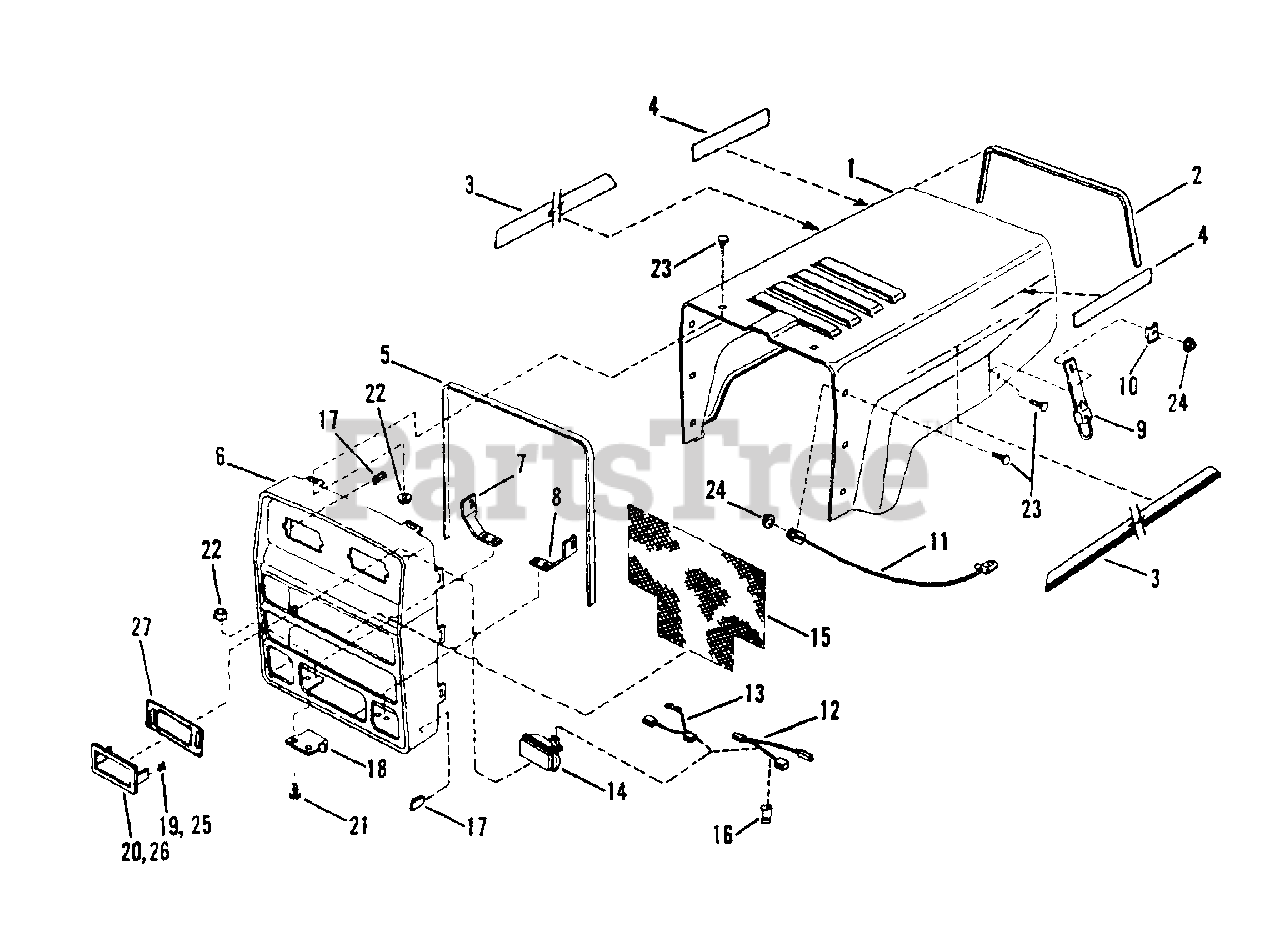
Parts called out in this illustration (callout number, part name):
1	HOOD, YT Series Tractor
2	TRIM, Hood
3	DECAL, Stripe
4	DECAL, Snapper
5	GASKET, Grill
6	GRILL
7	BRACE, Grill, R.H.
8	BRACE, Grill, L.H.
9	LATCH, Hood Retaining
10	CLIP, Hood Retainer
11	CABLE, Hood Stop
12	HARNESS, Head Lamp Wiring
13	HARNESS, Head Lamp Ground Wiring
14	HEAD LAMP
15	MESH, Grill
16	CLIP, Wiring Harness
17	CLIP
18	HINGE, Hood
19	CLIP, Head Lamp Mounting (Use 7017591 Wire Retainer & 7033211)
20	BEZEL, Head Lamp Mount (Use 7033211 & 7017591)
21	BOLT, 1/4-20 x 5/8" Hex Flange Lock, Grade 5
22	NUT, 1/4-20 Hex Flange Lock
23	BOLT, 1/4-20 x 5/8" Flat Head Carriage
24	NUT, 1/4-20 Hex Fl. Top Lock
26	BEZEL (Has a slot or hole in retainer tang)
27	REINFORCEMENT, Bezel
